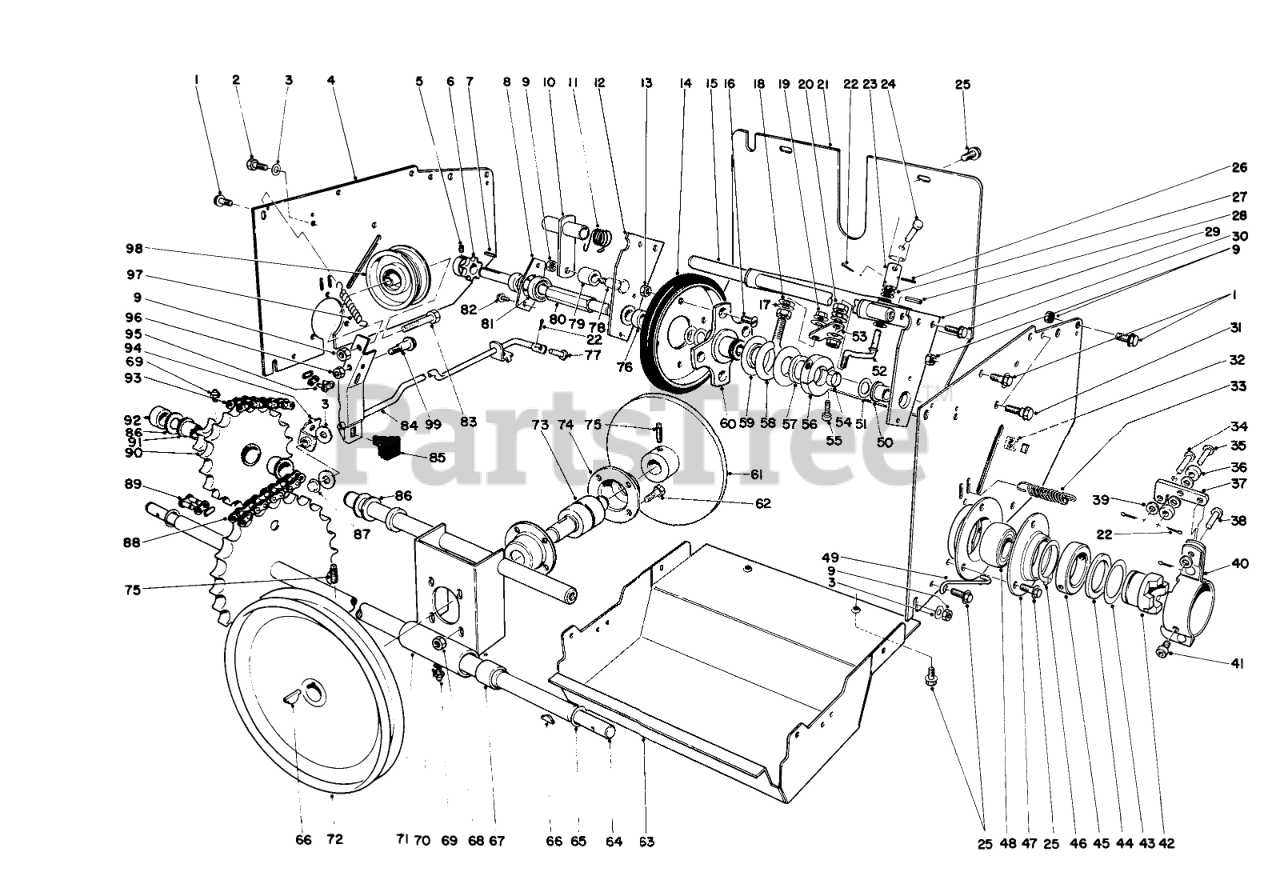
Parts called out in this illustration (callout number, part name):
1	SCREW-HH
2	SCREW-HHFTF
3	WASHER-FLAT
4	Side Plate Drive
5	SCREW-HSH
6	SPROCKET
8	BEARING CUP
9	NUT-LOCK, NI
10	CHAIN TENSION ARM WA
11	TORSION SPRING
12	HEX SHAFT MOUNT R
13	NUT-LOCK, NI
14	FRICTION WHEEL
15	Bracket Dead Shaft
16	5/16-18X5/8 FLT HD MS
17	Washer
18	WASHER-SPRING
19	NUT-LOCK, FLANGE
20	NUT-LOCK
21	REAR COVER R
22	PIN-COTTER
23	U JOINT TUBE
24	CLEVIS PIN
25	SCREW-HWH
26	PIN-SPRING
27	Clevis Pin
28	PIN-ROLL
29	Hex Shaft Mounting (Incl. Ref. #50)
30	SCREW-HWHTF
31	SHOULDER SCREW
32	Retained Nut
33	EXTENSION SPRING
34	PIN-CLEVIS
35	PIN-CLEVIS
36	CLUTCH ROLLER
37	CLUTCH CAM ARM
38	PIN-CLEVIS
39	WASHER-FLAT
40	CLUTCH MT BRKT ASM
41	SCREW-HSH
42	WHEEL CLUTCH
43	THRUST WASHER
44	THRUST BEARING
45	CLUTCH MOUNT COLLAR
46	RING-RETAINING, EXTERNAL
47	BEARING FLANGE
48	BEARING
49	CLUTCH RETAINER
50	BUSHING
51	WASHER-FLAT
52	CONNECTION ROD
53	SHIFT ROD PIVOT
54	SPLIT SPACER
55	SCREW-HSH
56	ColIar
57	WASHER-THRUST
58	SLIDER RING COLLAR
59	SLIDER RING
60	TRACTION DISC HUB
61	FRICTION PLATE O
62	SCREW-HH
63	LOWER SHIELD R
64	AXLE SHAFT WA
65	WASHER
66	KEY-WOODRUFF
67	Bearing
68	NUT-KEPS
69	FITTING-GREASE
70	WASHER-LOCK
71	Bulkhead (Incl. Ref. #67)
72	Pulley
73	Friction Plate Shaft
74	HOUSING BEARING
75	Set Screw
76	SPACER
77	PIN-CLEVIS
78	SHOULDER BOLT
79	CHAIN TENSION ROLLER
80	FRICTION WHEEL SHAFT
81	BEARING
82	SCREW
83	SCREW-HH
84	Auger Brake Assembly (Incl. Ref. #85)
85	Brake Pad
86	WASHER-THRUST
87	PUSH NUT
88	Lower Chain (Incl. Ref. #89)
89	LINK-CHAIN
90	Sprocket (Incl. Ref. #69 & 91)
91	3/4ID X 3/4LG BSHG
92	SPACER-IDLER
93	UpperChain (Incl. Ref. #95)
94	Bracket-Clutch
95	LINK-CONNECTING
96	NUT-LOCK, CONE
97	SPRING
98	PULLEY-IDLER
99	BOLT-SHOULDER
